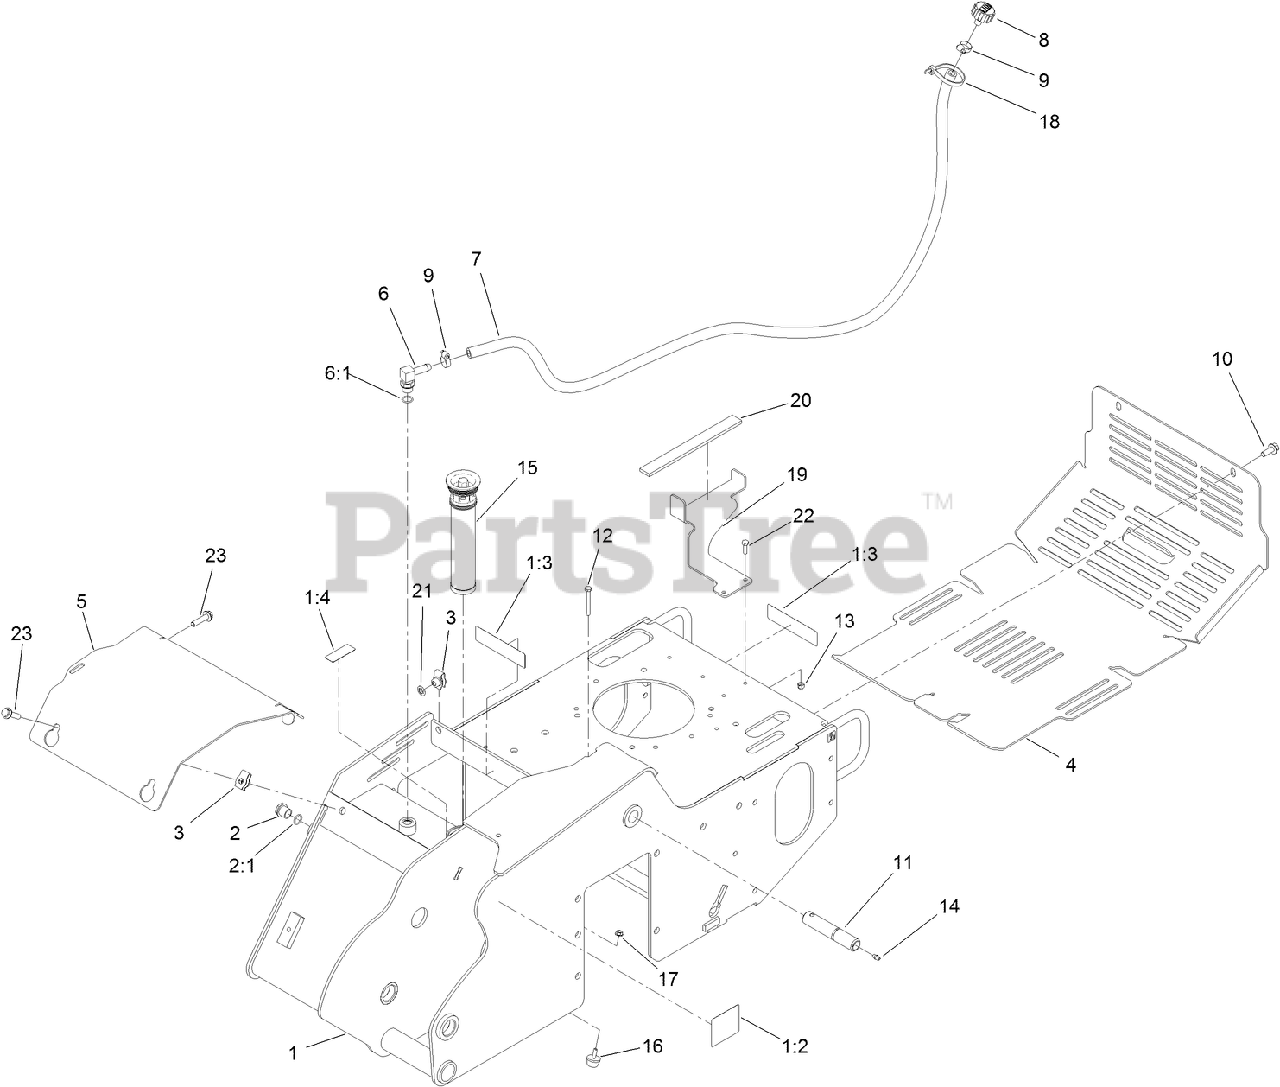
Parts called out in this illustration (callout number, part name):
1	MAIN FRAME ASM
1:2	DECAL-WARNING
1:3	DECAL-DANGER
1:4	DECAL-OIL, HYD
2	SIGHT GLASS ASM
2:1	O-RING
3	NUT-TINNERMAN
4	COVER-REAR
5	PLATE-COVER, FRONT
6	FITTING-ELBOW, 90
6:1	O-RING
7	HOSE-BREATHER
8	BREATHER
9	CLAMP-HOSE
10	SCREW-HHF
11	PIN-PIVOT
12	SCREW-HH
13	NUT-LOCK, NI
14	FITTING-GREASE
15	IN-TANK FILTER ASM
16	BUMPER
17	NUT-HF
18	TIE-CABLE
19	BRACKET-TANK
20	PAD-FOAM
21	NUT-PUSH
22	SCREW-HH
23	SCREW-HHF
